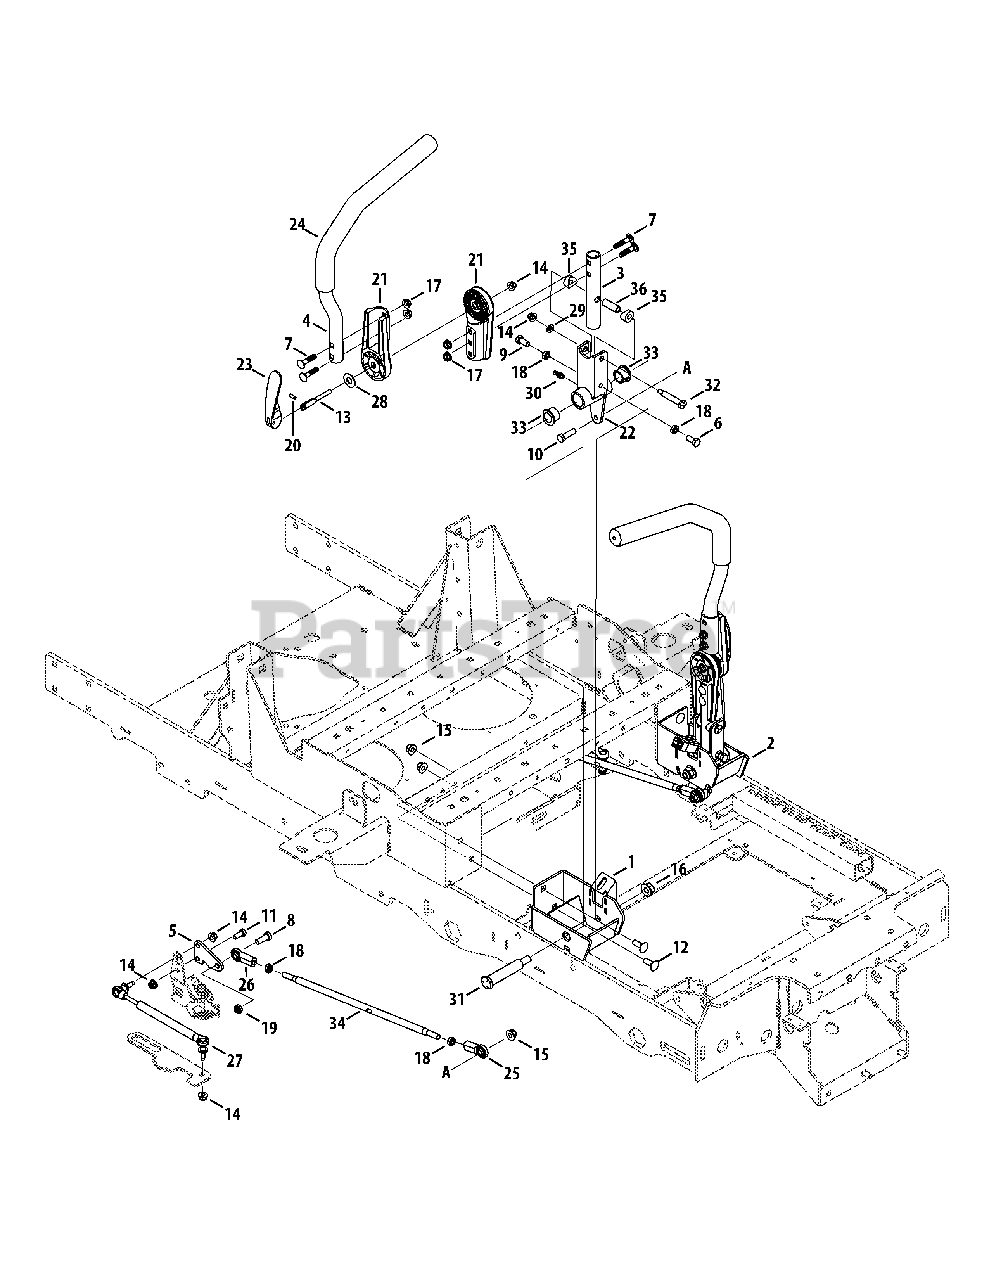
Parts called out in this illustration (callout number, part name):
1	Pivot Housing Weldment, RH
2	Pivot Housing Weldment, LH
3	Lower Pivot Tube Weldment
4	Lapbar Tube Weldment
5	Return to Neutral Control Bracket
6	Hex Cap Screw, 3/8-24 x .750
7	Carriage Bolt, 5/16-18 x 1.50
8	Hex Cap Screw, 3/8-16 x 1.00
9	Hex Cap Screw, 3/8-24 x .875
10	Hex Cap Screw, 3/8-16 x 1.25
11	Hex Cap Screw, 5/16-18 x .75
12	Carriage Bolt, 3/8-16 x 1.00
13	Bolt, 5/16-18 x 2.73
14	Nut, 5/16-18, Flangelock
15	Nut, 3/8-16, Flnagelock
16	Nut, 1/2-13, Flangelock
17	Nut, 5/16-18, Centerlock
18	Jam Nut, 3/8-24
19	Jam Nut, 3/8-16
20	Roll Pin, .188 x .500
21	Handle Adjustment
22	Pivot Control
24	Grip, 1.0 ID
25	Ball Joint, 3/8-24, RH
26	Ball Joint, 3/8-24, LH
27	Damper Control Cylinder
28	Bevel Washer, .525 x 1.00 x .050
29	Washer, .330 x .630 x .064
30	Grease Fitting, 1/4-28
31	Shoulder Bolt, .75 x 3.25, 1/2-13
32	Shoulder Screw, .375 x 1.813, 5/16-18
33	Bearing, .75 x 1.00 x .73
34	Control Rod
35	Spacer, .500 x .875 x .250
36	Spacer, .385 x .5000 x 1.40
